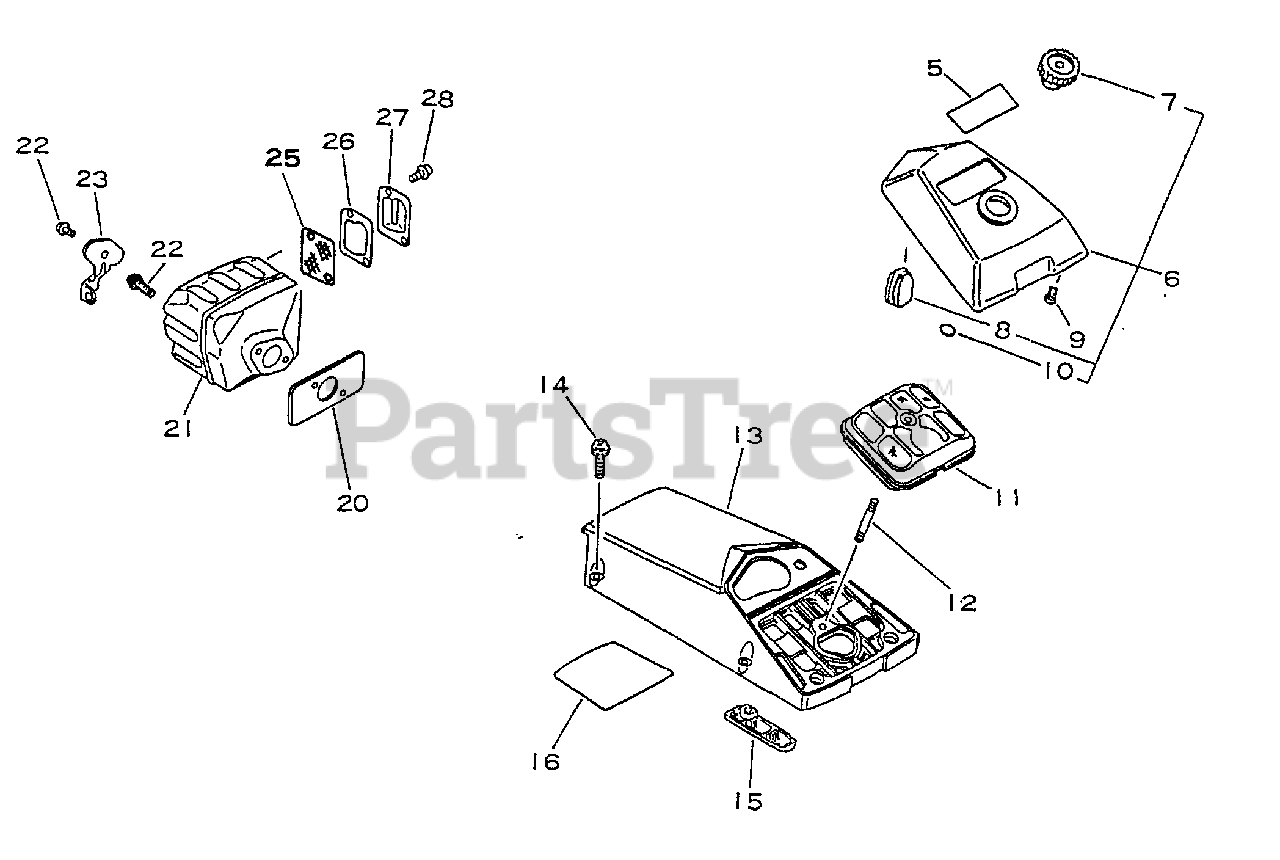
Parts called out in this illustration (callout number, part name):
5	LABEL - MODEL
6	COVER, AIR FILTER
7	THUMBNUT
10	O-RING - 11
11	FILTER, AIR
13	COVER, ENGINE
14	SCREW - 5X20
15	FILTER, AIR
16	COVER, ENGINE
20	GASKET, EXHAUST
21	MUFFLER
22	SCREW - 5X10
23	BRACKET, MUFFLER
25	SCREEN, SPARK ARRESTOR
26	GASKET, EXHAUST
27	LID, MUFFLER
28	SCREW - 4X8
